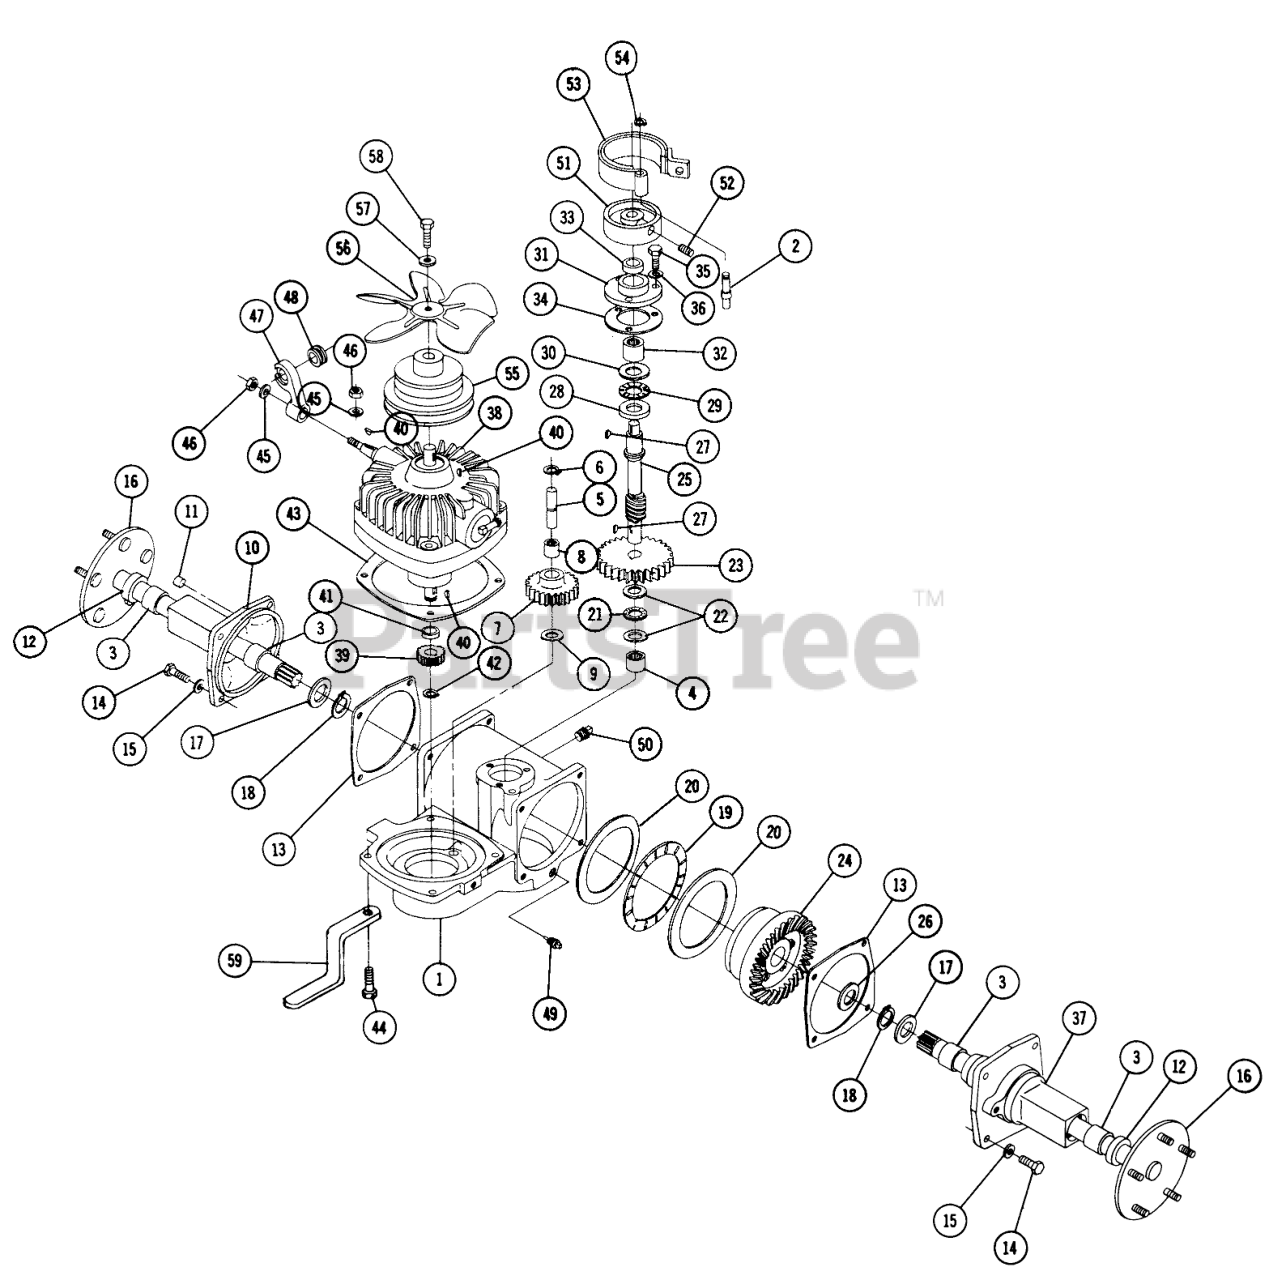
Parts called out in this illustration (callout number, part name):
1	Housing
3	BEARING-NEEDLE
4	BEARING-NEEDLE
9	RACE THRUST
14	Bolt 3/8-16 x 1
16	Axle
24	BULLT 325
27	KEY WOODRUFF
30	Rae-Thrust
35	Bolt 5/16-18 x
36	Lockwasher
37	Housing Axle L.H.
38	Engine Speed Control
40	KEY WOODR 1/8X1/2 DI
44	Bolt Hex 3/8-16 x 5
45	Washer
46	3/8-16 E.S.
48	Grommet-Rubber
49	Plug 1/4 Pipe
52	Screw 1/4-20 x 5/8
56	FAN
58	Bolt Hex 1/4-20 x 1 1/4 Nylok
59	Bracket
